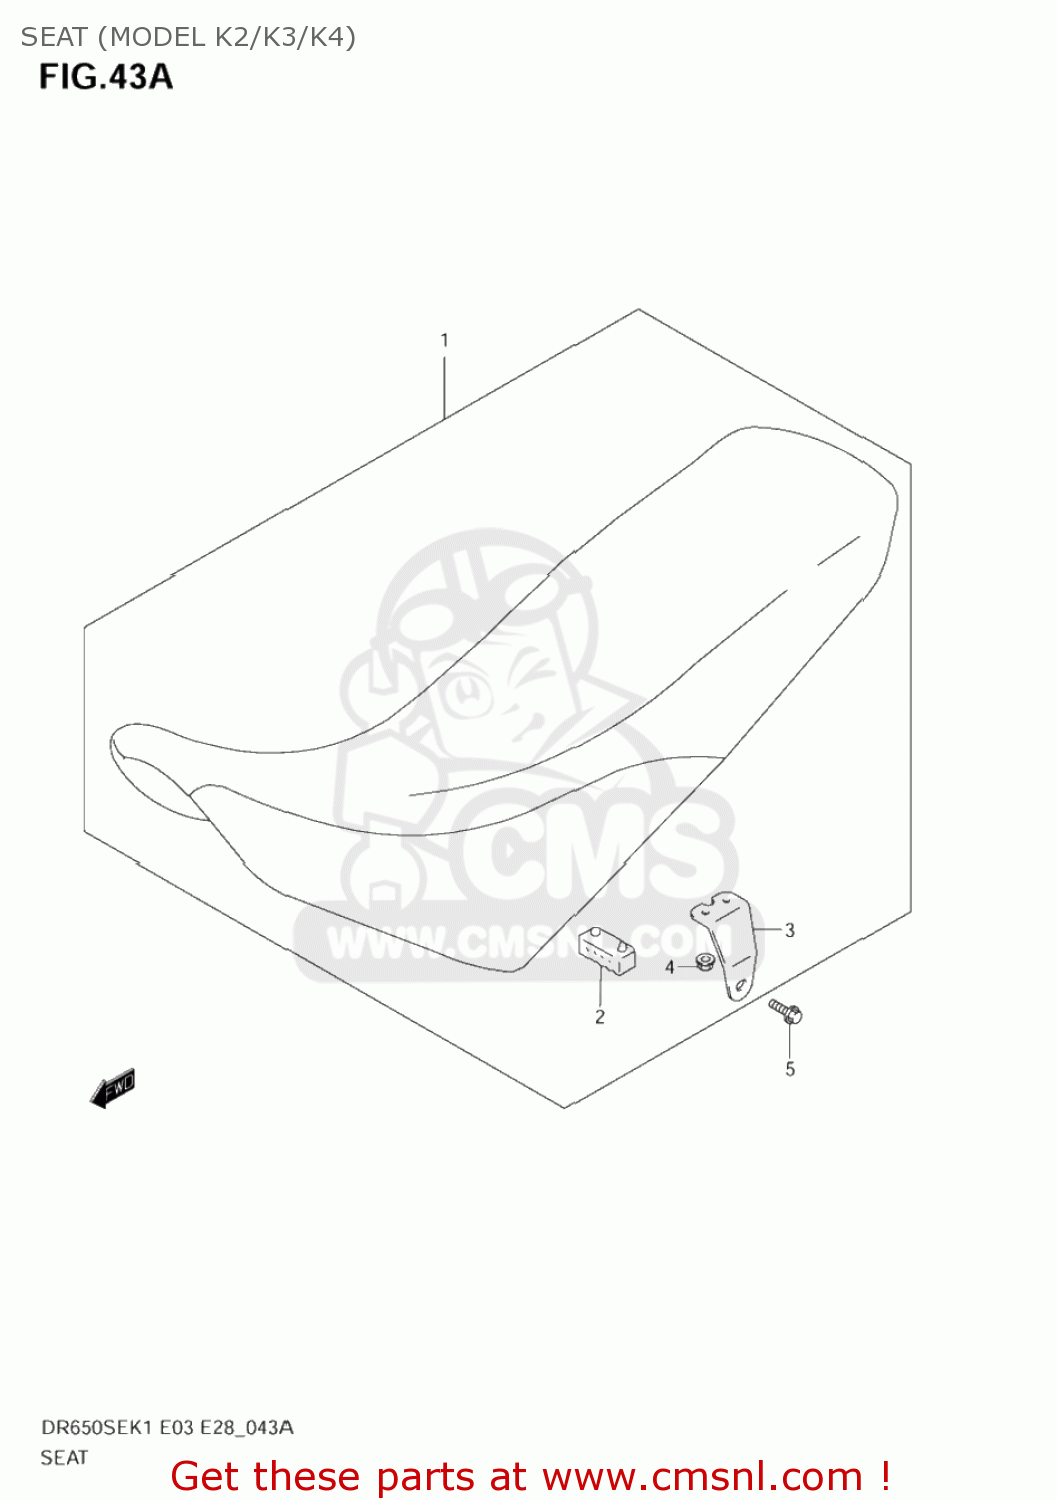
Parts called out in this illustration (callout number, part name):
1	SEAT SET
2	CUSHION,SEAT(40X20X15)
3	BRACKET
4	NUT
5	BOLT
